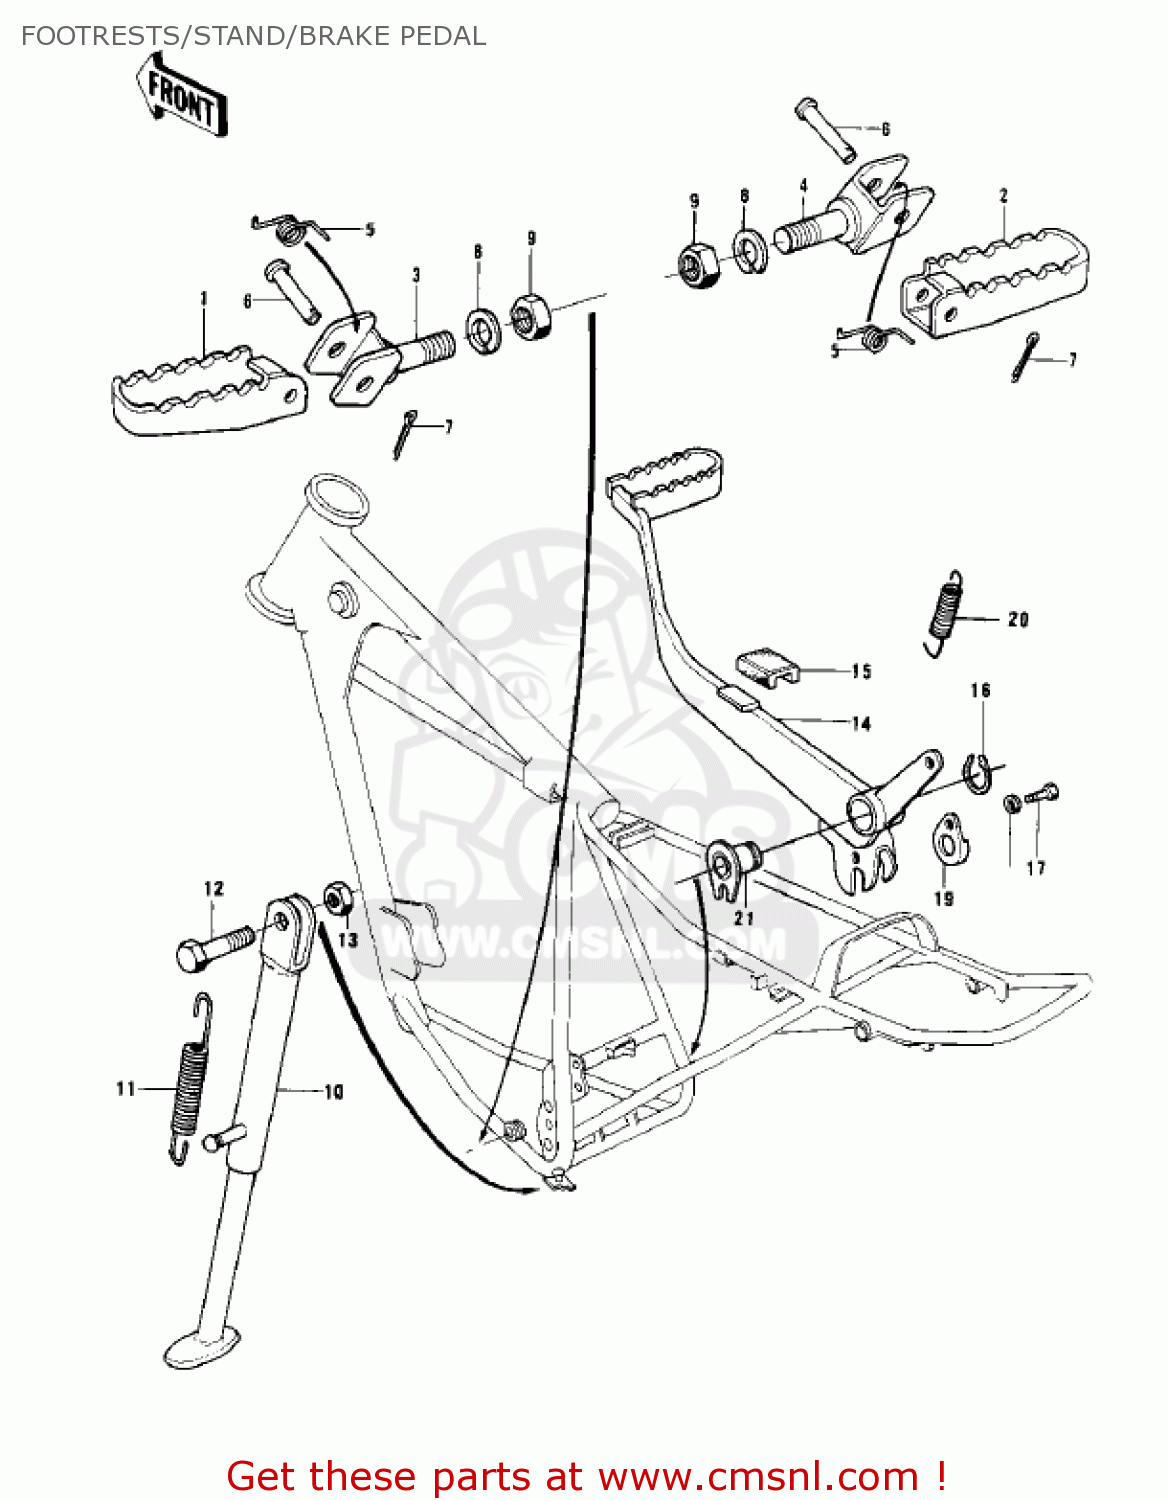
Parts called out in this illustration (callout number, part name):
1	FOOTREST BAR,LH
2	FOOTREST BAR,RH
3	BRACKET,FOTRST BAR,LH
4	BRACKET,FOTRST BAR,R
5	FOOTREST BAR SPRING
6	PIN-FOOTREST BAR FIT
7	PIN COTTER,295X15
8	WASHER-SPRING,14MM
9	NUT,14MM
10	STAND,SIDE
11	SPRING,SIDE STAND
12	BOLT,HEX HEAD,10X35
13	NUT,10MM
14	LEVER-BRAKE,PEDAL
15	DAMPER,BRAKE PEDAL
16	CIRCLIP-TYPE-C,22MM
17	SCREW-PAN-CROS,5X8
18	WASHER-SPRING,6MM
19	BRACKET,BRAKE PEDAL
20	SPRING,BRAKE PEDAL
21	COLLAR,BRAKE PEDAL
